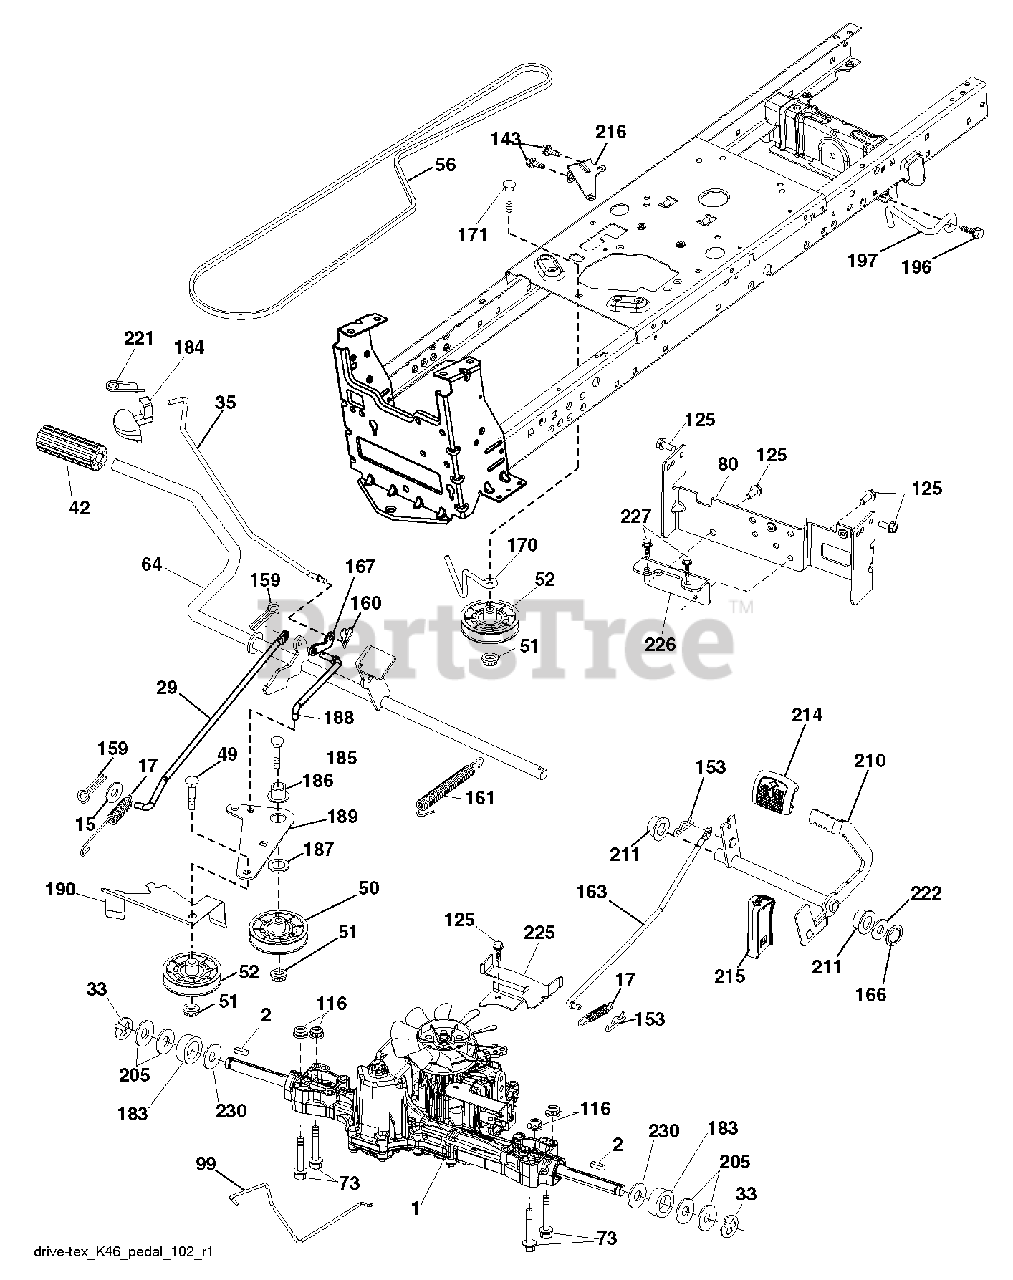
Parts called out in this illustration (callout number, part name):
2	SQUARE KEY
15	WASHER
17	SPRING.BRAKE.K46.GREEN
29	ROD.BRAKE.K46
35	ROD.CNTRL.PARK.PREDATOR.LT.TEX
42	PEDAL COVER T
50	IDLER.FLAT.910.OFFSET
51	NUT LOCK FLG 3/8-16 UNC
52	IDLER.V-GROOVE.910.OFFSET
56	V-BELT.MOWER.92.40.42/K46
64	SHAFT.ASM.PEDAL.BRK.CNTR
80	STRAP.TORQUE.K46.K57R.TT
99	ROD.SPRING.BYPASS.K46.LT.Z
116	NUT LOCK HEX FLANGE 5/16-18
125	SCREW
143	SCREW LT
153	RETAINER M
159	COTTER PIN
160	RETAINER CLIP
161	SPRING, RETURN LT
163	ROD.CONTROL.K57R.K46
166	NUT.PUSH.625
167	LATCH.BRAKE.SPRING
170	KEEPER.V-IDLER.CENTER.
183	SPACER AXLE
184	HANDLE.PARKING.BRK.PRED.LT.RED
186	SPACER.RETAINER
187	WASHER 12/32X2X10GA
188	RP LINK.CLUTCH.GROUND.DRIVE
189	BELLCRANK.GROUND.DRIVE.TEX.
190	KEEPER.BELLCRANK.DRIVE
196	SCREW 3/8-16X1
197	LINK.CLUTCH.ANIT-ROTAT
210	ROCKER.ASM.PEDAL.CONTR
211	BEARING.NYLON
214	PEDAL.FORWARD.PAD.TEX
215	PEDAL.REVERSE.TEX.GT.4
216	BRACKET.PULLEY.IDLER.W/TEX
221	RETAINER.SPRING.CLIP.H
222	WASHER 21/32 X 1-1/4 X 10 GA.
225	KEEPER.BELT.TRANSAXLE.K46
226	BRACKET.MOUNT.TORQUE.K46.TLT
227	SCREW
230	WASHER.HARDENED
